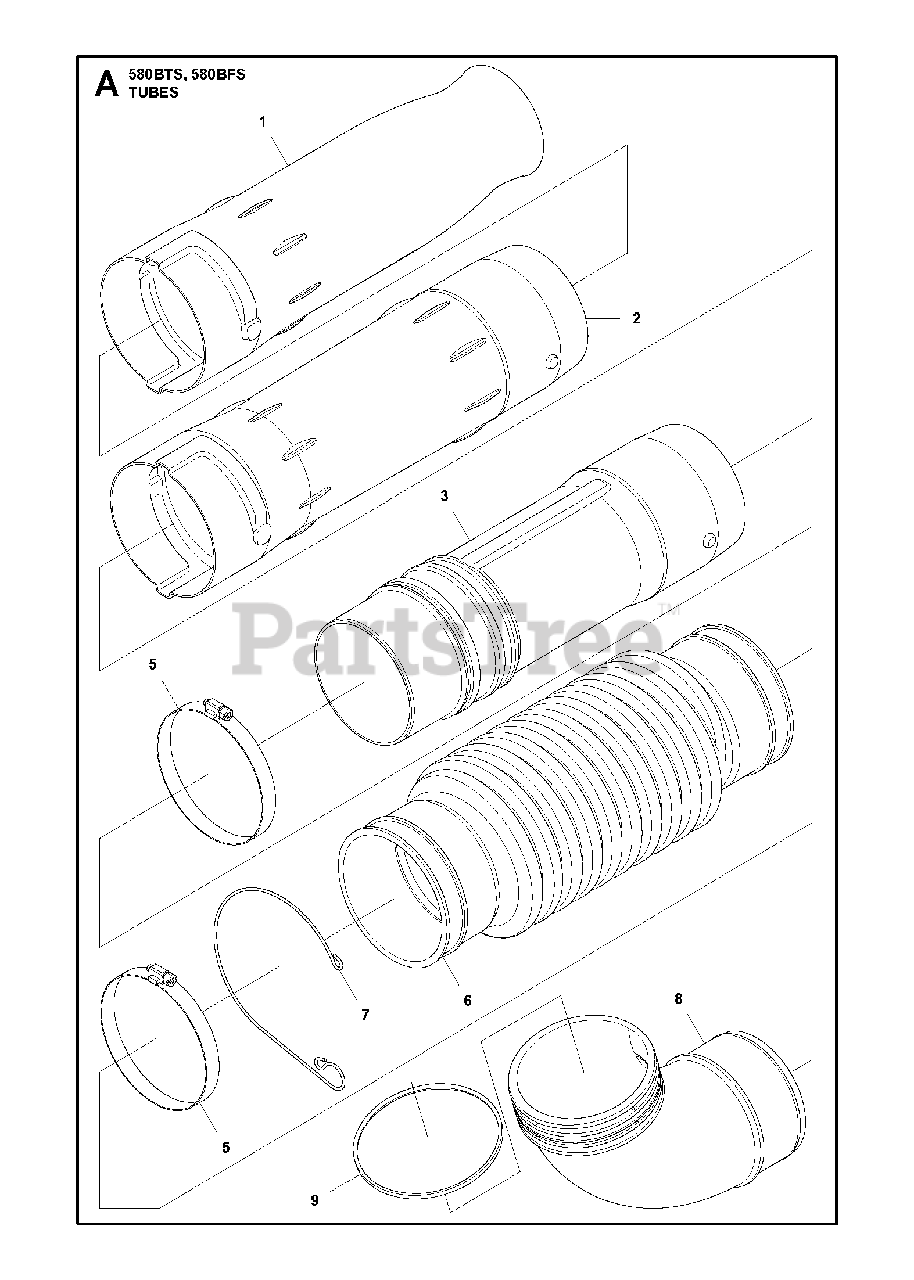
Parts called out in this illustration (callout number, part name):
2	PIPE STRAIGHT
3	SWIVEL JOINT
5	CLAMP(F115)
6	HOSE
8	PIPE ELBOW
